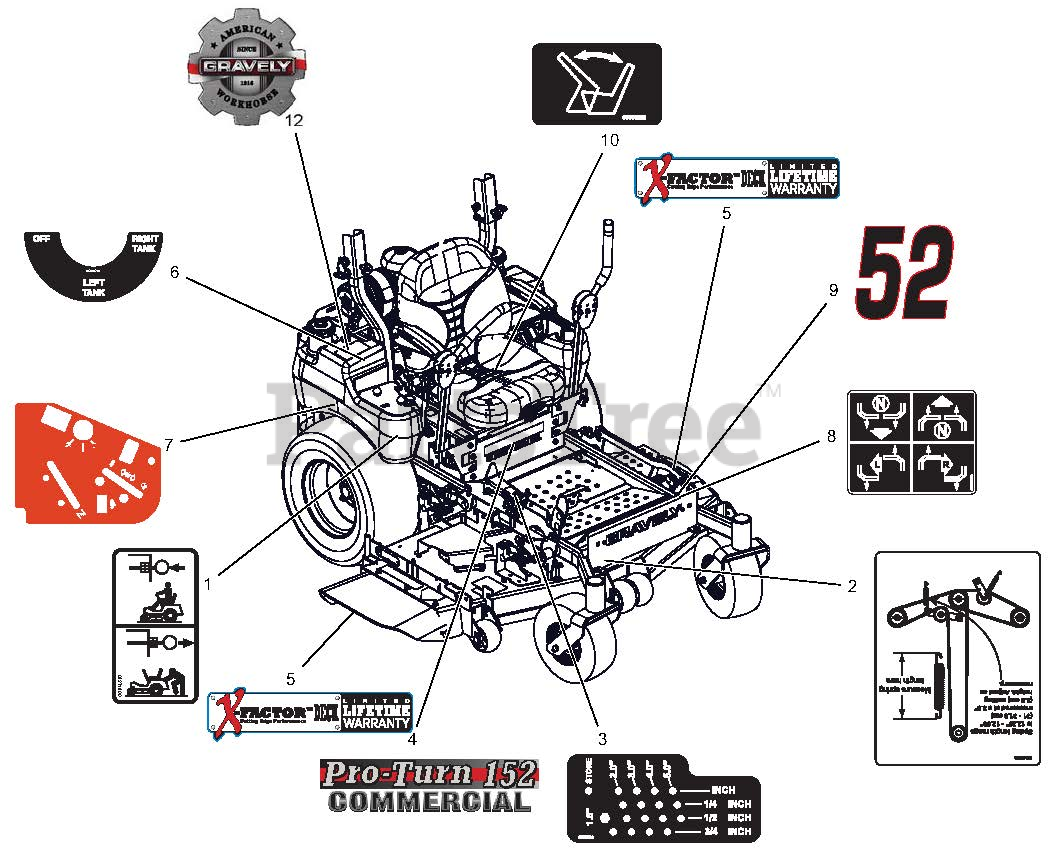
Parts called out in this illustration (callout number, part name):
1	DECAL, TRANSMISSION DISCONNECT
2	DECAL, BELT ROUTING
3	DECAL, HEIGHT OF CUT
4	DECAL, PRO-TURN 152
5	DECAL, X-FACTOR DECK
6	DECAL, FUEL VALVE
7	PANEL, PT100 CONTROL
8	DECAL, INSTRUCTIONAL - STEERING
9	DECAL, 52"
10	DECAL, SEAT RELEASE
12	DECAL, GRAVELY HERITAGE-LARGE
